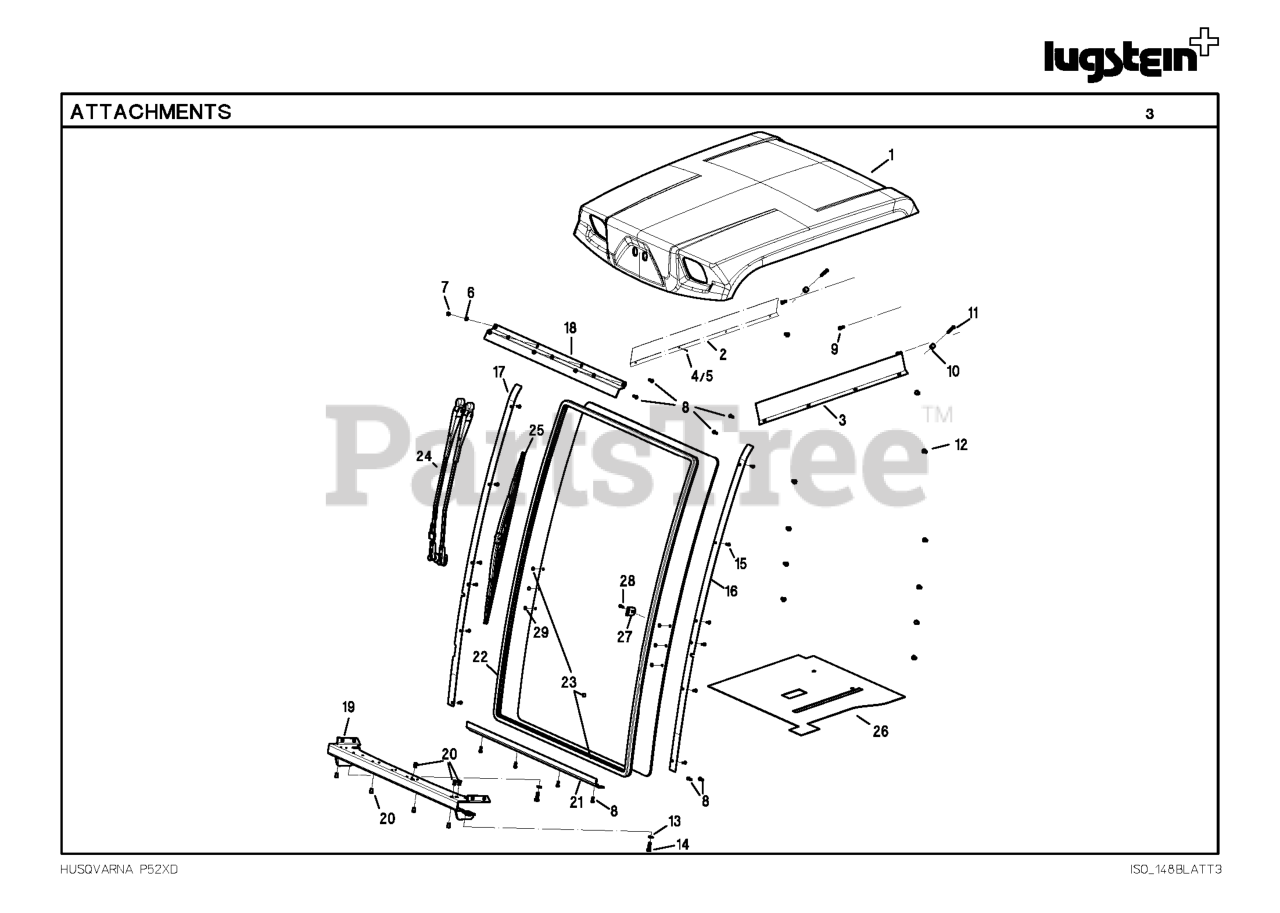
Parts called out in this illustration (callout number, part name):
5	WASHER
6	WASHER
7	LOCKNUT M6
8	Screw
9	Screw
11	SCREW M6S 6X30
13	WASHER BRB 8.4X17
14	SCREW M6S 8X25
